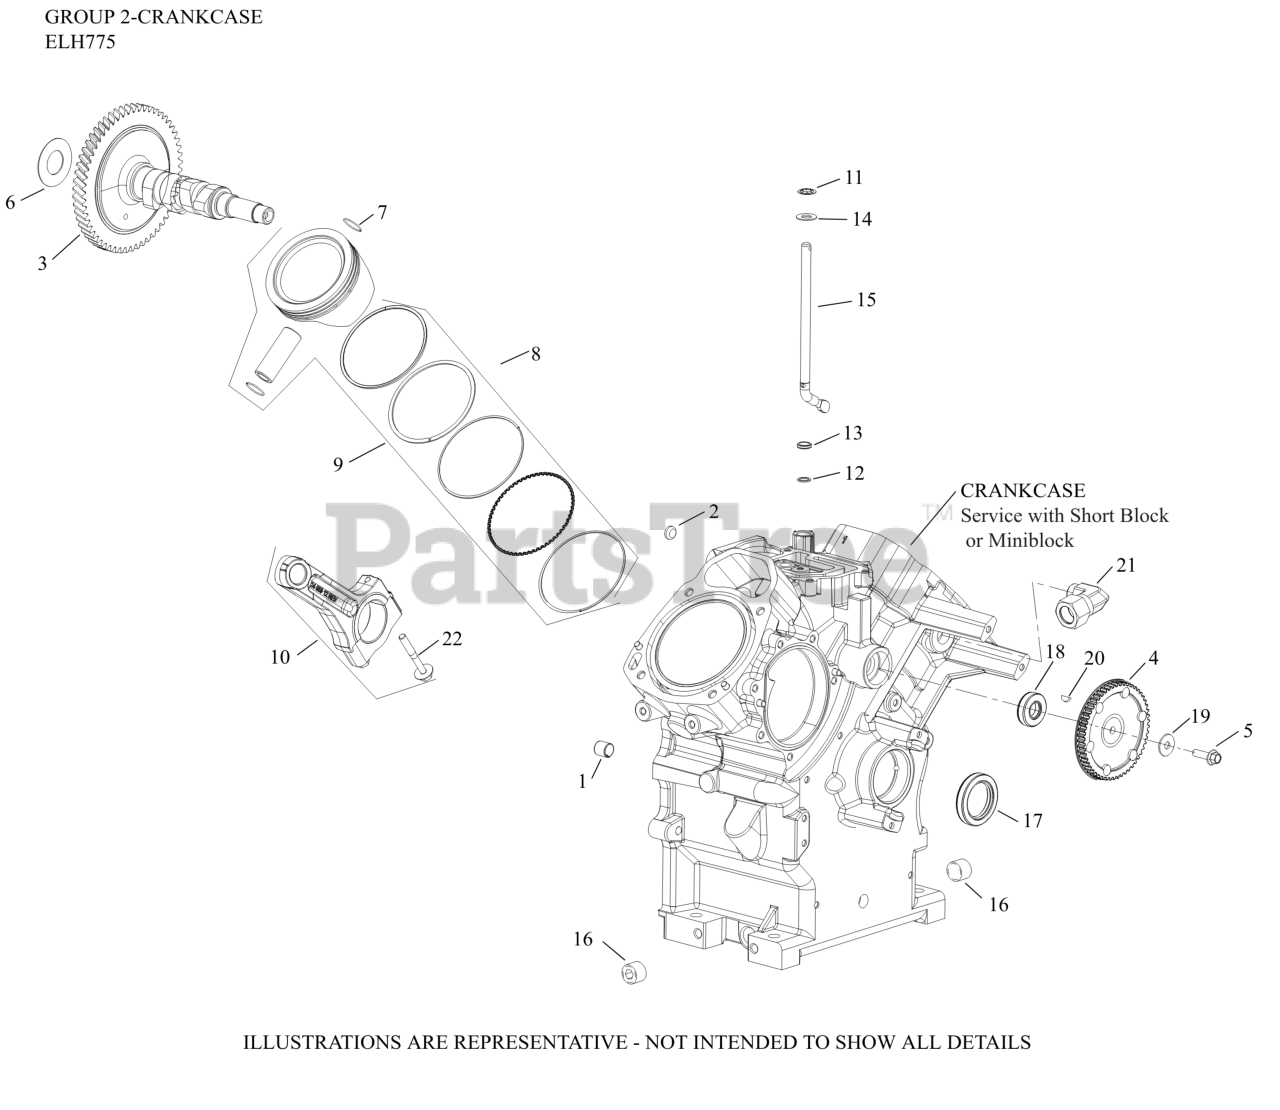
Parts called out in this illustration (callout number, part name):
1	PIN, LOCATING
2	PLUG, CUP
3	KIT, CAMSHAFT-EFI
4	SPROCKET, CAMSHAFT
5	SCREW, FLG M6x1.0x20
6	SHIM, CAMSHAFT (WHITE .028")
6	SHIM, CAMSHAFT (BLUE .03")
6	SHIM, CAMSHAFT (RED .032")
6	SHIM, CAMSHAFT (YELLOW .034")
6	SHIM, CAMSHAFT (GREEN .036")
6	SHIM, CAMSHAFT (GRAY .038")
6	SHIM, CAMSHAFT (BLACK .04")
7	RETAINER, PISTON PIN
8	RING SET(STD)STYLE B-1.2mm Tp RING THICK
8	RING SET(.08)STYLE B-1.2mm RING THICK
8	RING SET(.25)STYLE B-1.2mm Tp RING THICK
8	RING SET(.50)STYLE B-1.2mm Tp RING THICK
9	KIT,PSTN/RNG STYLE B(STD)
9	KIT,PSTN/RNG STYLE B(.08)
9	KIT,PSTN/RNG STYLE B(.25)
9	KIT,PSTN/RNG STYLE B(.50)
10	ROD, ASSEMBLY CONNECTING
11	RETAINER, RING
12	WASHER, FLAT 11/32"
13	SEAL, GOVERNOR CROSS SHAFT
14	WASHER, FLAT 9 MM
15	SHAFT, GOVERNOR CROSS
16	PLUG, PIPE CTSK 3/8"
17	SEAL, OIL (HELIX LIP)
18	SEAL, CAMSHAFT
19	WASHER, FLAT 1/4"
20	KEY, 3/32" X 3/8"
22	KIT, ROD BOLTS-(#25086677S)
